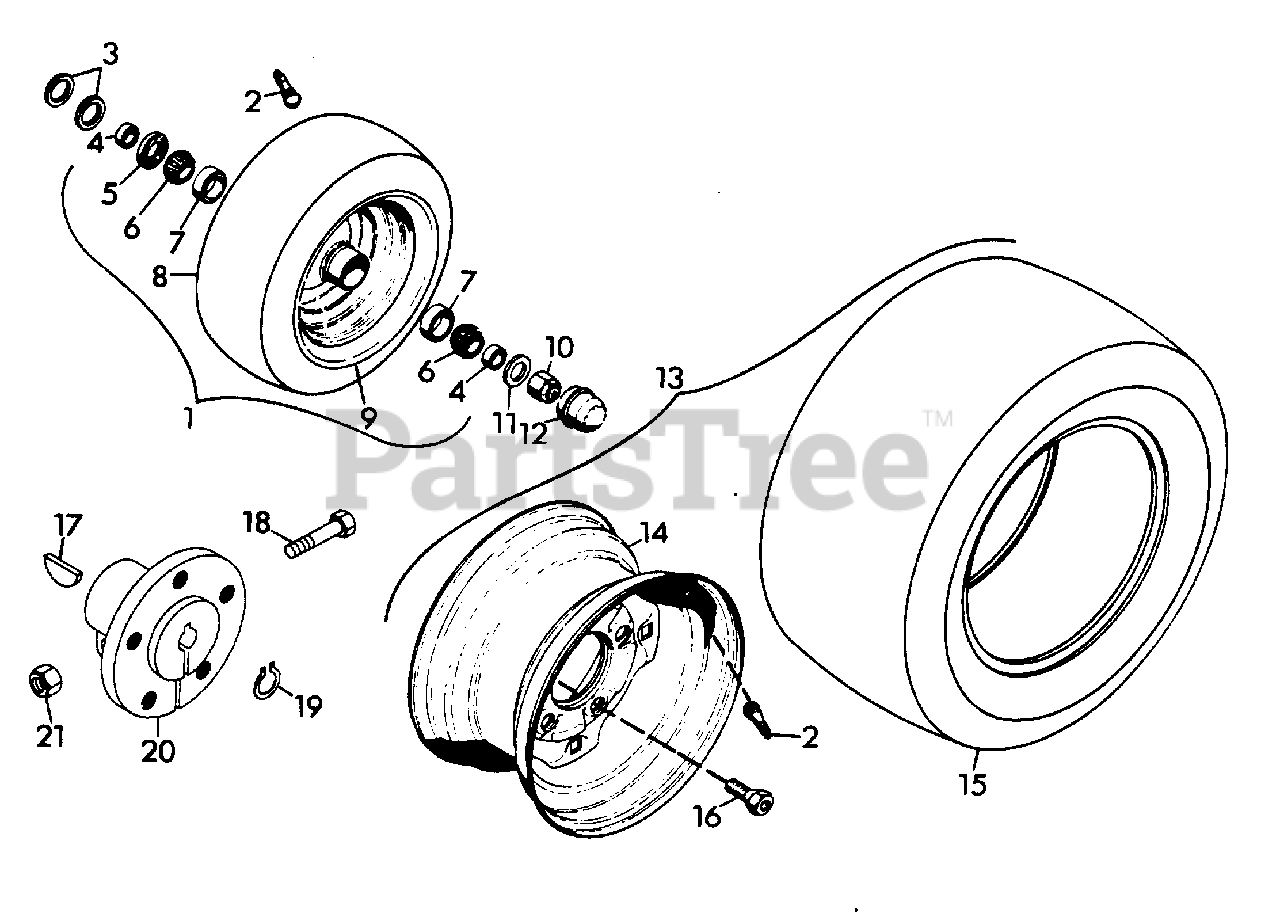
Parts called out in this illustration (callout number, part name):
1	ASSEMBLY, FRONT TIRE
2	ASSEMBLY, VALVE STEM
3	WASHER, FLAT .813X1.37X.100
4	SPACER
5	SEAL, OIL
6	BEARING, CONE LM 11949
7	BEARING, CUP LM 11910
8	TIRE, FRONT
9	RIM, FRONT WHEEL
10	NUT, LOCK 5/8-11
11	WASHER, FLAT .656X1.312X.095
12	CAP
13	ASSEMBLY, REAR TIRE
14	RIM, REAR WHEEL
15	TIRE, REAR
16	BOLT, HUB 7/16-20X.75(SPECIAL)
17	KEY, WOODRUFF .312X2.125
18	BOLT, HEX 1/2-13X2.00
19	RING, RETAINING 1.250 SHAFT
20	HUB, LOCKING WHEEL
21	NUT, LOCK 1/2-13
